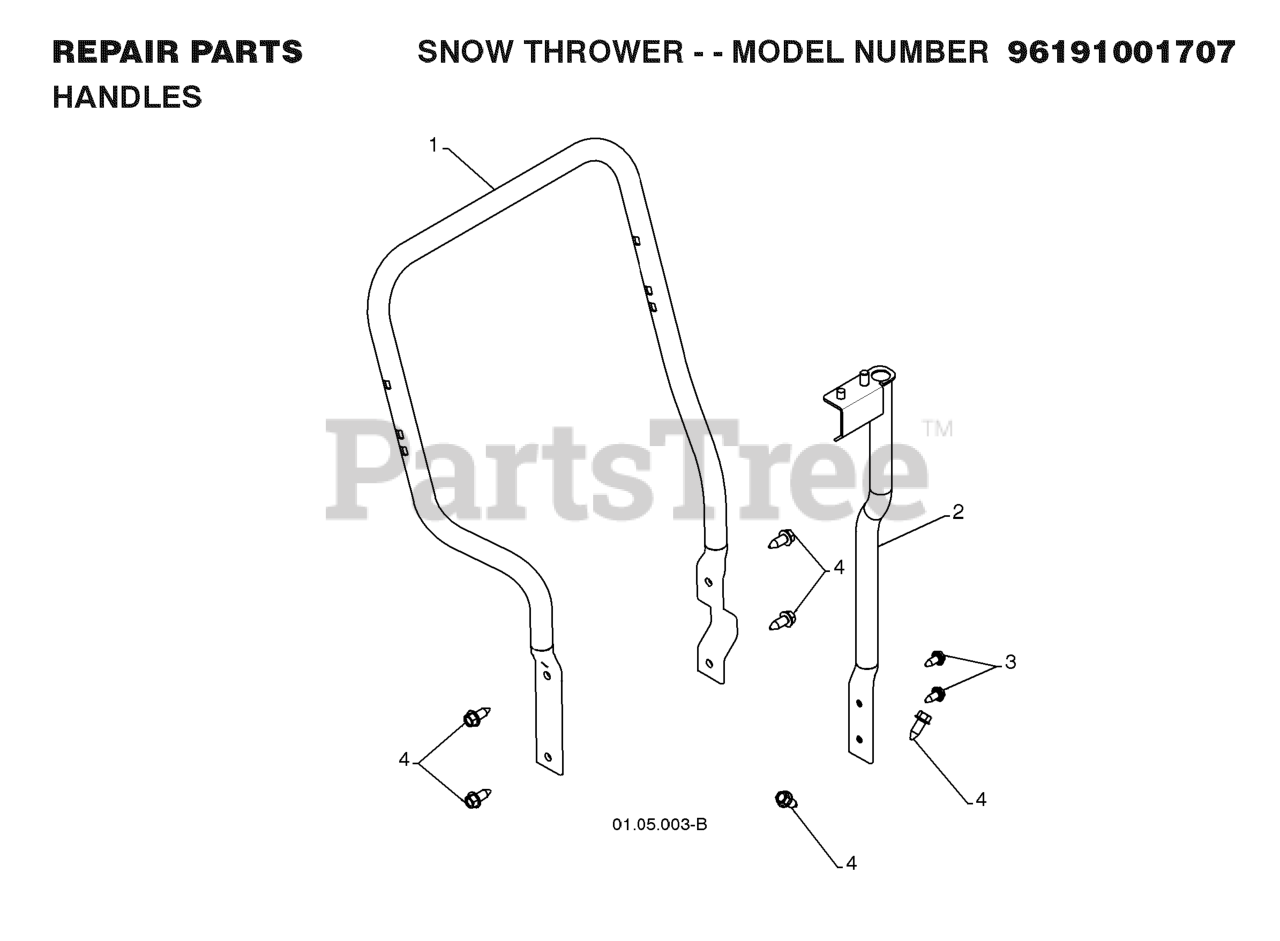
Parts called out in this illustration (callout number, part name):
1	TUBE.LOWER.HANDLE.SNOW.BLACK
2	SUPPORT.WELDMENT.ROTATOR.
3	SELF-TAPPING SCREW 5/16-18X3/4
4	SCREW 3/8-16X1
